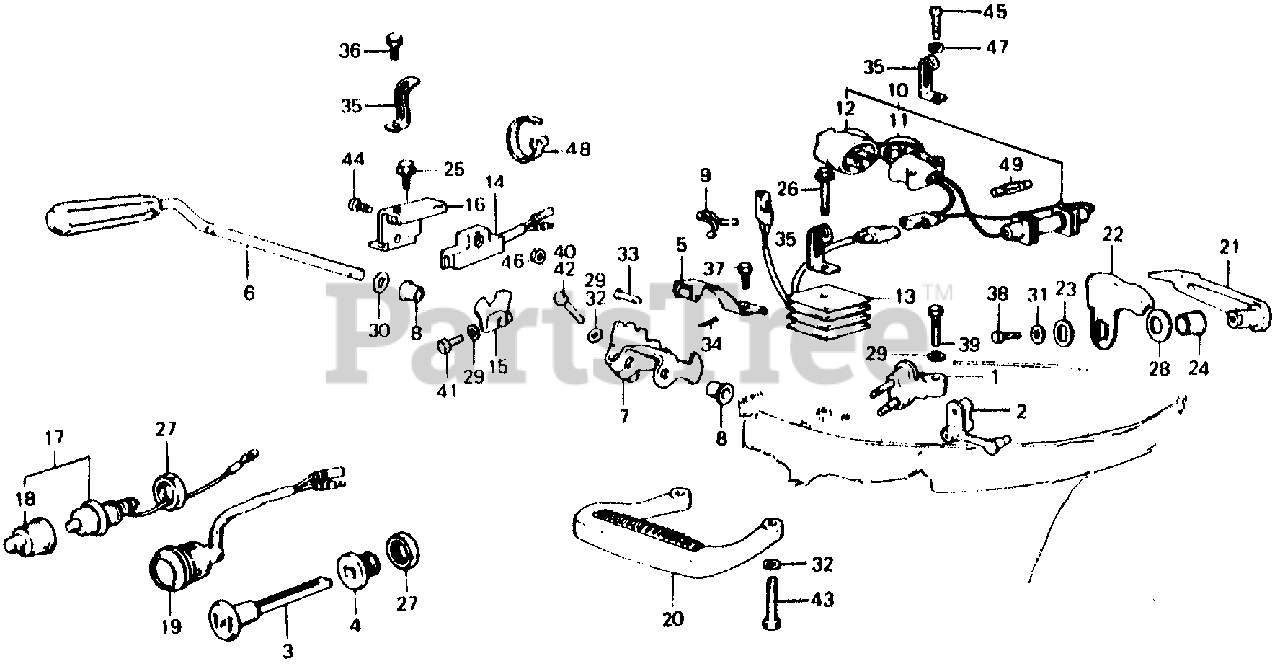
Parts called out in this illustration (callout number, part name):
1	CONNECTOR, FUEL *B9* (ATLANTIS BLUE) (NOT AVAILABLE)
3	KNOB, CHOKE
4	GUIDE, CHOKE KNOB
5	SPRING, CLICK
6	SHAFT, SHIFT
7	ARM, GEARSHIFT (NOT AVAILABLE)
8	BUSH, SHAFT
10	RECEPTACLE ASSY., LAMP
11	RECEPTACLE (NOT AVAILABLE)
12	PLUG, RECEPTACLE (NOT AVAILABLE)
13	RECTIFIER ASSY. (NOT AVAILABLE)
14	SWITCH ASSY., NEUTRAL
15	PLATE, SWITCH SHIELD
16	PLATE, SWITCH SETTING
19	LAMP ASSY., INDICATOR
19	LAMP, INDICATOR
20	HANDLE, CARRYING *B9* (ATLANTIS BLUE) (NOT AVAILABLE)
21	LEVER, COVER LOCK *B9* (ATLANTIS BLUE) (NOT AVAILABLE)
22	HOOK, COVER LOCK
23	WASHER, COVER LOCK
24	BUSH, COVER LOCK
25	BOLT, FLANGE (6X12)
26	BOLT, FLANGE (6X35)
27	NUT, HEX. (16MM)
28	SPRING, LEVER
29	WASHER, PLAIN (6MM)
30	WASHER, PLAIN (10MM)
31	WASHER (6MM)
32	WASHER, PLAIN (8MM)
33	PIN (5X17)
34	PIN, SPLIT (1.6MM)
35	CLIP B, CORD
36	BOLT, HEX. (6X8)
37	BOLT, HEX. (6X12)
38	BOLT, HEX. (6X16)
39	BOLT, HEX. (6X20)
40	BOLT, HEX. (6X25)
41	BOLT, HEX. (6X28)
43	BOLT, HEX. (8X32) (NOT AVAILABLE)
44	SCREW, PAN (5X20)
45	SCREW, PAN (5X22)
46	NUT, HEX. (5MM)
47	WASHER, PLAIN (5MM)
48	BAND B1, WIRE
49	FUSE A (5A)
